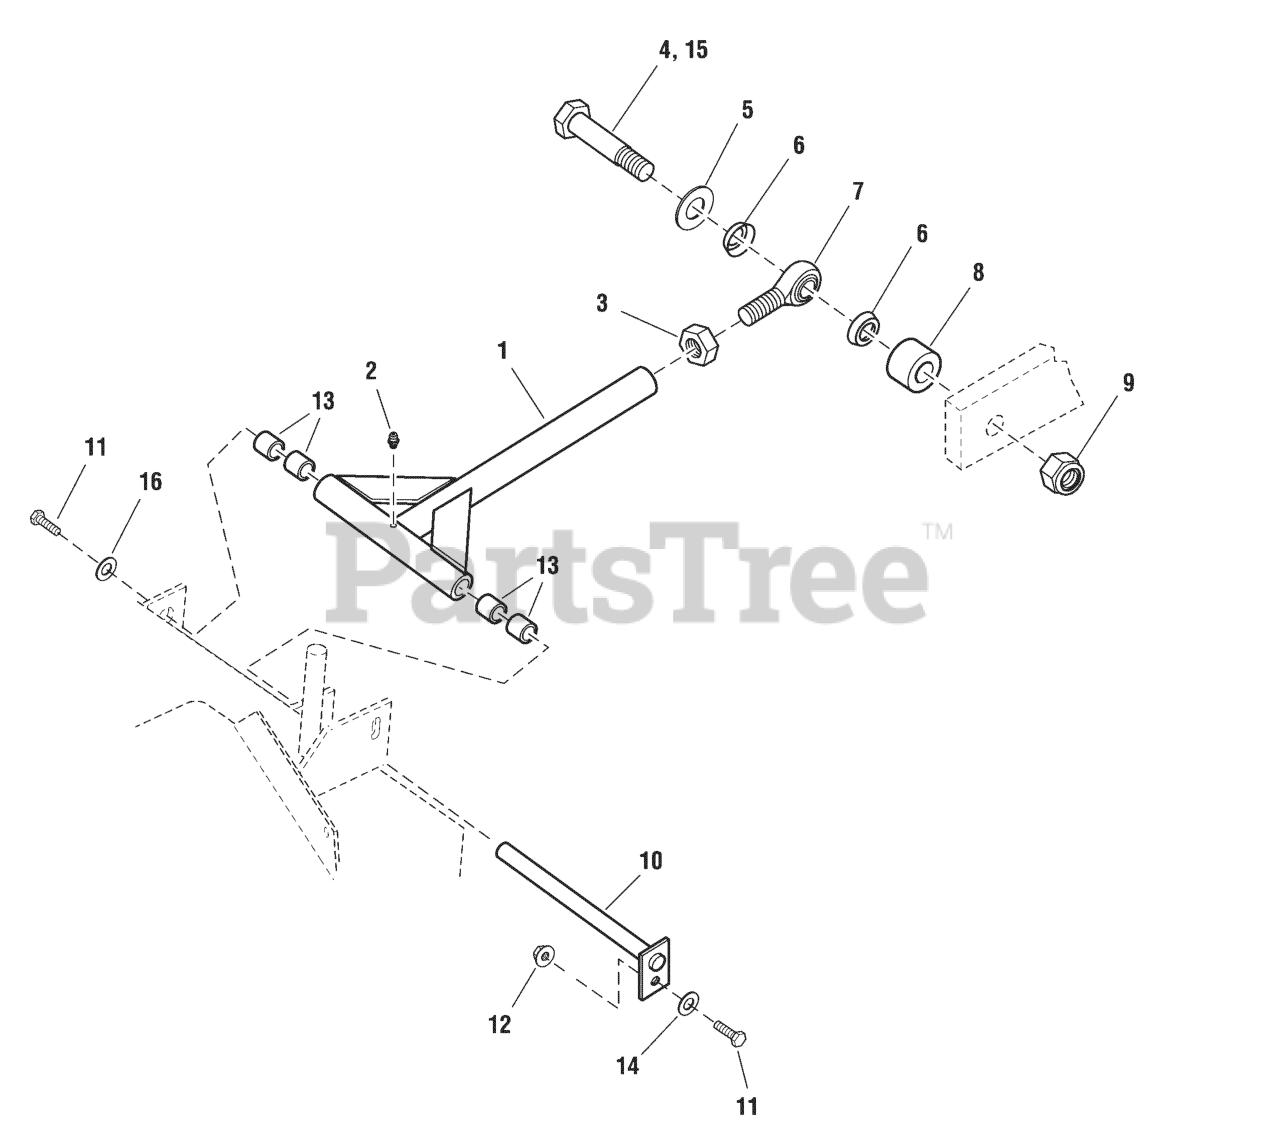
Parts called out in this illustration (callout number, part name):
1	WELD, PUSHER BAR - RED
2	GREASE FITTING, 1/4-28 STRAIGHT
3	NUT, 3/4-16 HEX JAM
4	BOLT, 3/4-16 X 3-1/2" YZ GD5
5	WASHER, 3/4 SAE
6	SEAL, 3/4" ROD END
7	BALL JOINT, 3/4-16, MALE
8	SPACER, .75 X 1.50 X 1.00
9	NUT, 3/4-16 HEX NYLON LOCK
11	BOLT, 3/8-16 X 1" GD5 CZ
12	NUT, 3/8-16 HEX NYLOCK FLANGE
13	BUSHING, .75 X 1.00 X 1.00, PLASTIC
14	WASHER, 3/8 SAE
15	BOLT, 3/4-16 X 3" YZ GD5
16	WASHER, .390 X 1.50 X .109 YZ
